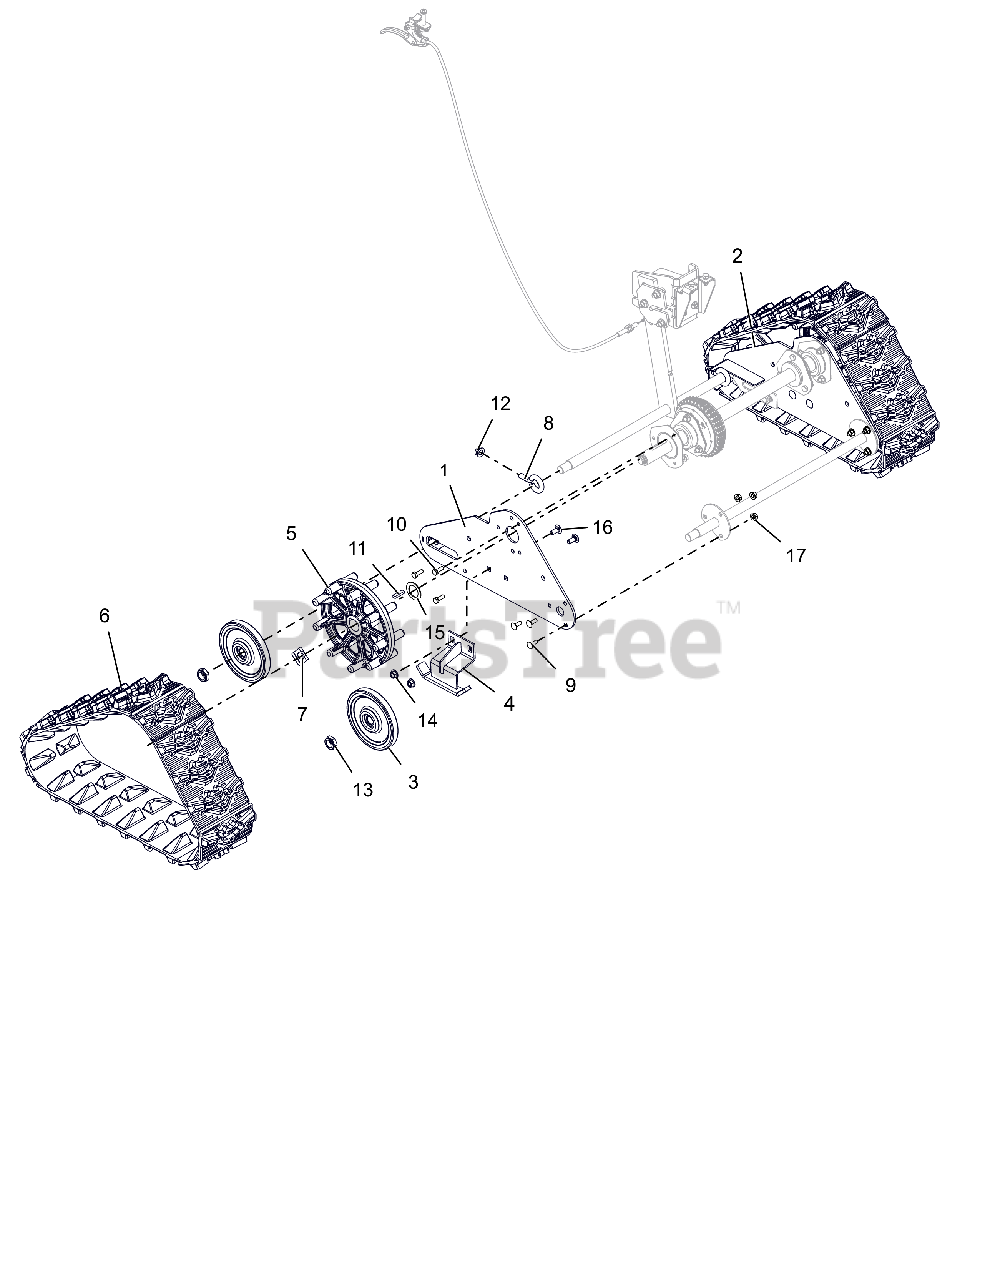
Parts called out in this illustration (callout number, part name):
1	SIDE PLATE, RH-TRACK
2	SIDE PLATE, LH-TRACK
3	WHEEL, BOGIE - SINGLE BEARING
4	RUNNER, GUIDE-TRACK
5	WHEEL, MACHINED DRIVE
6	TRACK, RUBBER
7	CLIP, SNAP .625 DIA
8	BLT-EYE .375-16X.880 YWZC
9	@BLT-RDHDSQNK .25-20X.75 G5YZ
10	@BLT-HEX .25-20X.75 GR5 YWZC
11	KEY-RECT .25X.188X1.00
12	NUT-LK-CTR-FLG .38-16 YWZC
13	@NUT-LK-NYL .625-18 YWZC
14	@NUT-LK-TOP-FLG .31-18 YWZC
15	WSHR-FL-STL 1.010X1.505X.062YZ
16	@BLT-RDHDSQNK .31-18X.75 G5YZ
17	@NUT-LK-TOP-FLG .25-20 YWZC
